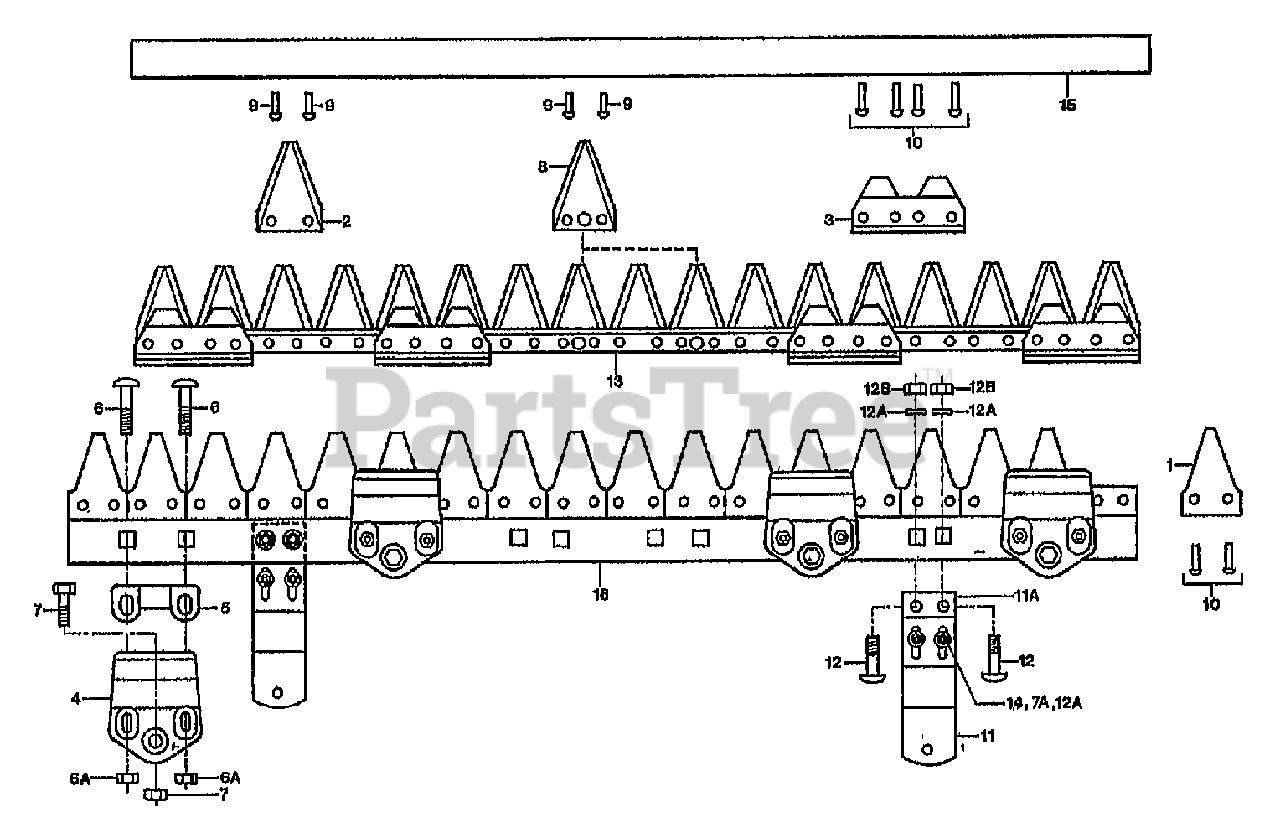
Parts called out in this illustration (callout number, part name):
1	LEDGER SECTION
2	BAR-CUTTER 2 HOLE BLADE SECTION
4	CLIP-BLADE GUIDE
6	SCR-CARR M8 X 40
6A	NUT-M8
7	SCR-HH M8 X 30
7A	NUT-M8 BRAKE
8	BLADE-SECTIONS 3 HOLES
9	RIVETS-CS90 5.3 X 14
11	BOTTOM HALF - HEIGHT ADJUSTERS
11A	TOP HALF - HEIGHT ADJUSTERS
12	SCR-CARR M8X30MM SQNK
12A	WASHER-FLAT 5/16 SAE
12B	NUT-NYLOC M8
13	ASSM-34" BLADE T/B SICKLEBAR
14	BOLT-U M8 HEIGHT ADJUST
15	SHIELD-PLASTIC CUTTERBAR
16	LEDGER BAR W/RIVET BLADE
16	KIT-MAINT TRAILBLAZER
